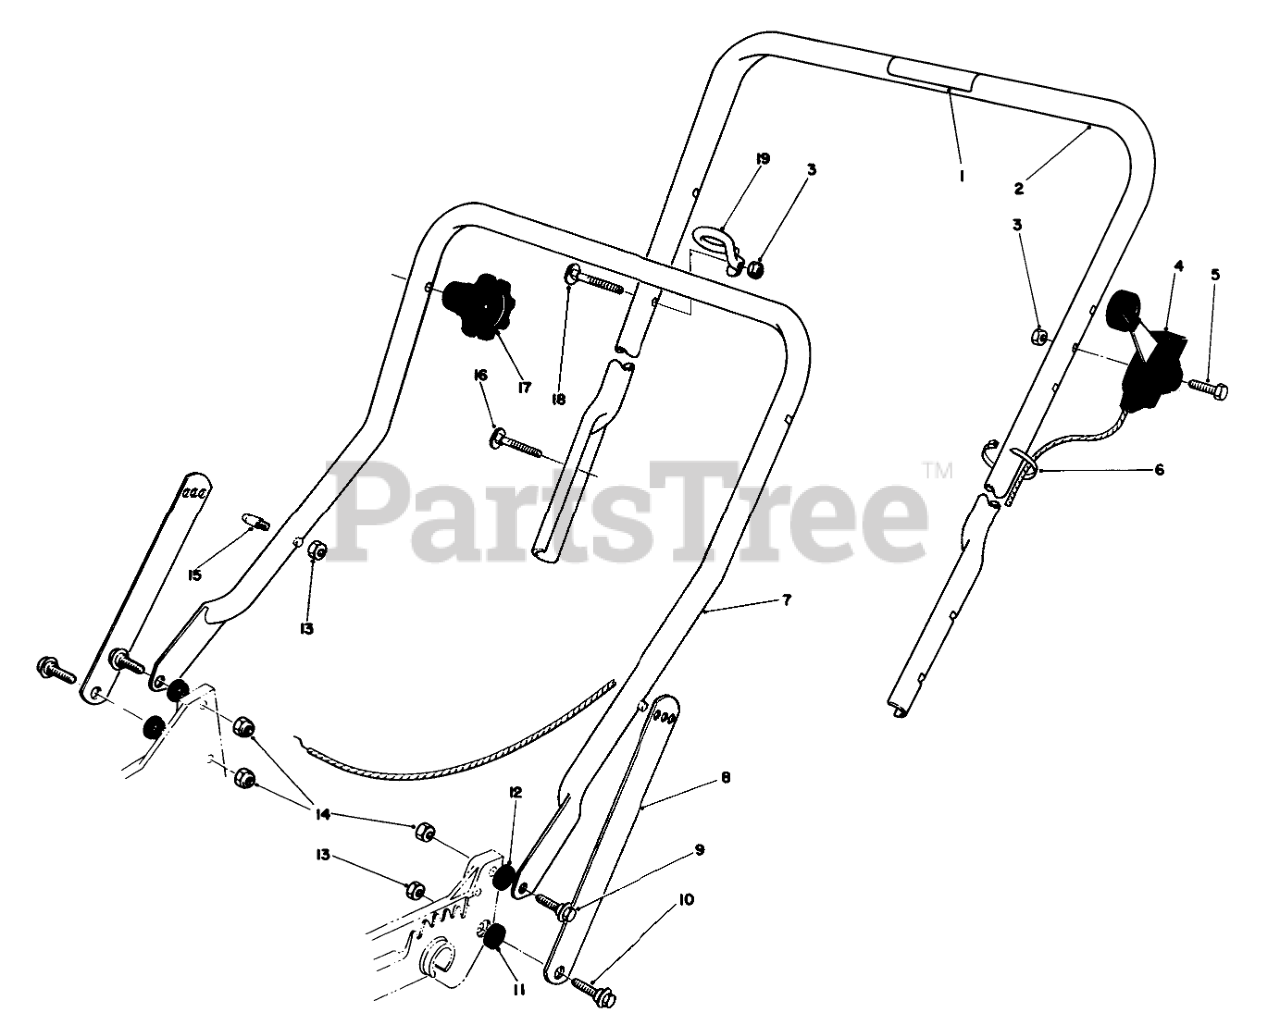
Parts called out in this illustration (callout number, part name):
1	Decal-Instructions
2	Handle-Upper (Incl. Ref. #1)
4	SERVICE THROTTLE CONTRO
5	SCREW-HH
6	TIE-CABLE
7	Handle-Lower
7	LOWER HANDLE ASM
8	Handle Latch
9	SCREW-SHOULDER
10	SCREW-SHOULDER
11	SPACER
12	SPACER
13	NUT-LOCK, NI
14	NUT-LOCK, NI
15	HANDLE PIN
16	5/16-18 X 2 HNDLE SCREW
18	HANDLE SCREW
19	Guide
